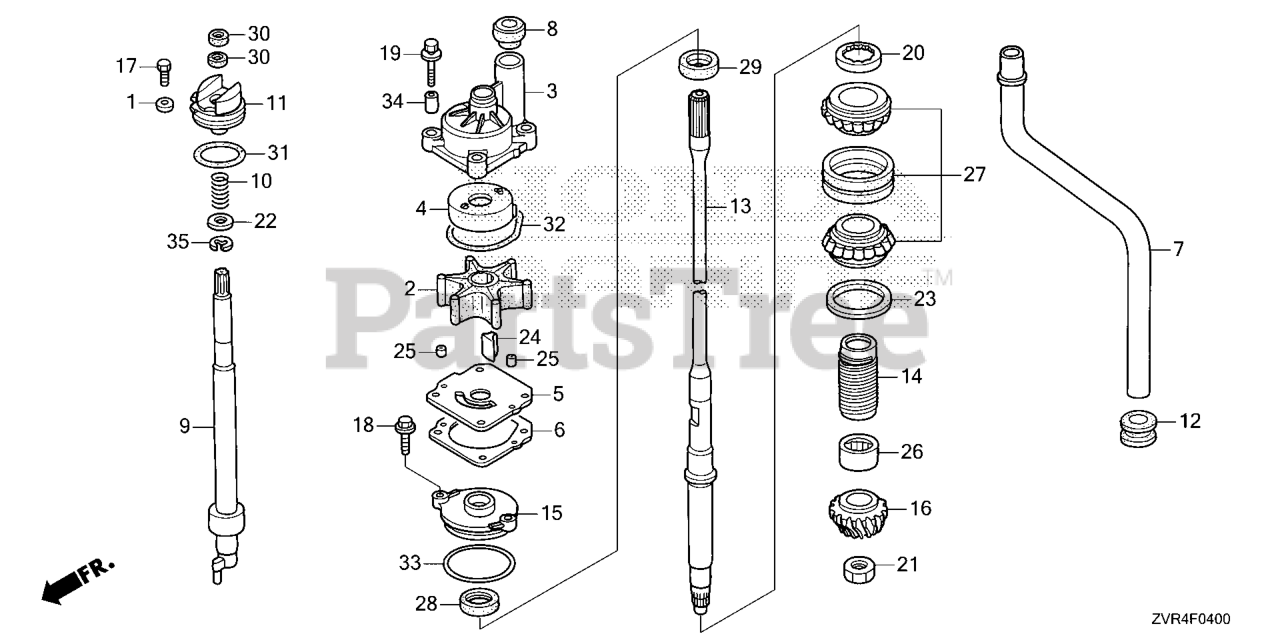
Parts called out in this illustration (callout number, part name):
1	WASHER, PIVOT
2	IMPELLER, PUMP
3	HOUSING, IMPELLER
4	LINER, PUMP
5	COVER, IMPELLER
6	GASKET B, IMPELLER
7	TUBE, WATER (XL)
8	RING, WATER TUBE SEAL
9	ROD, SHIFT
10	SPRING, SHIFT ROD
11	HOLDER, SHIFT ROD
12	GROMMET, EXTENSION CASE
13	SHAFT, VERTICAL (XL)
14	SLINGER, OIL
15	HOUSING, WATER SEAL
16	GEAR, PINION
17	BOLT, HEX. (6X12) Use up to Frame SN 1005248.
18	BOLT, FLANGE (6X20) (ENGINE NO.)
19	BOLT-WASHER (8X40)
20	NUT, LOCK (64MM)
21	NUT, HEX. (18MM)
22	WASHER, PLAIN (12MM)
23	SHIM A, GEAR (0.10)
23	SHIM B, GEAR (0.15)
23	SHIM C, GEAR (0.30)
23	SHIM D, GEAR (0.50)
24	KEY, WOODRUFF
25	PIN, DOWEL (6X10)
26	BEARING, NEEDLE (28.575X44.45X31.75)
27	BEARING, TAPER ROLLER (30X62X40)
28	SEAL, WATER (23X36X8)
29	SEAL, WATER (23X36X6)
30	SEAL, WATER (12X21X6)
31	O-RING (55.6X3.5)
32	O-RING, WATER PUMP
33	O-RING (58.5X3.5)
34	COLLAR, DISTANCE
35	E-RING (10MM)
